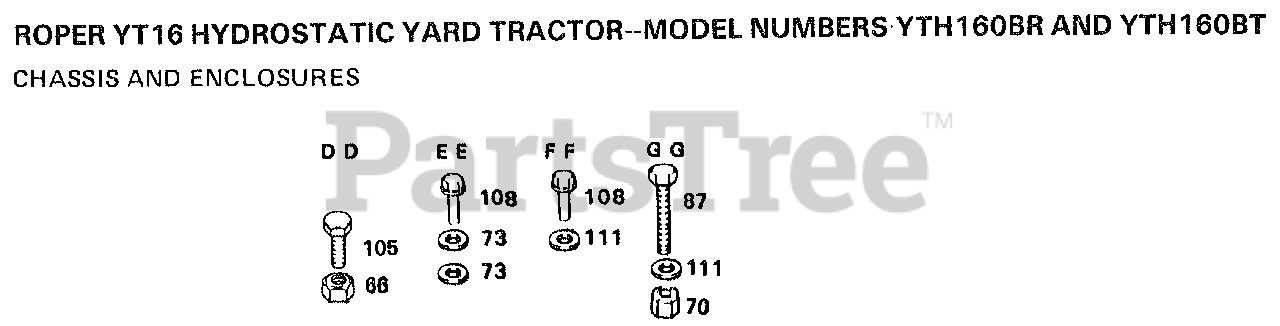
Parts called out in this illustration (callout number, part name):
73	WASHER
87	BOLT
108	SCREW GTV
111	WASHER HYT
